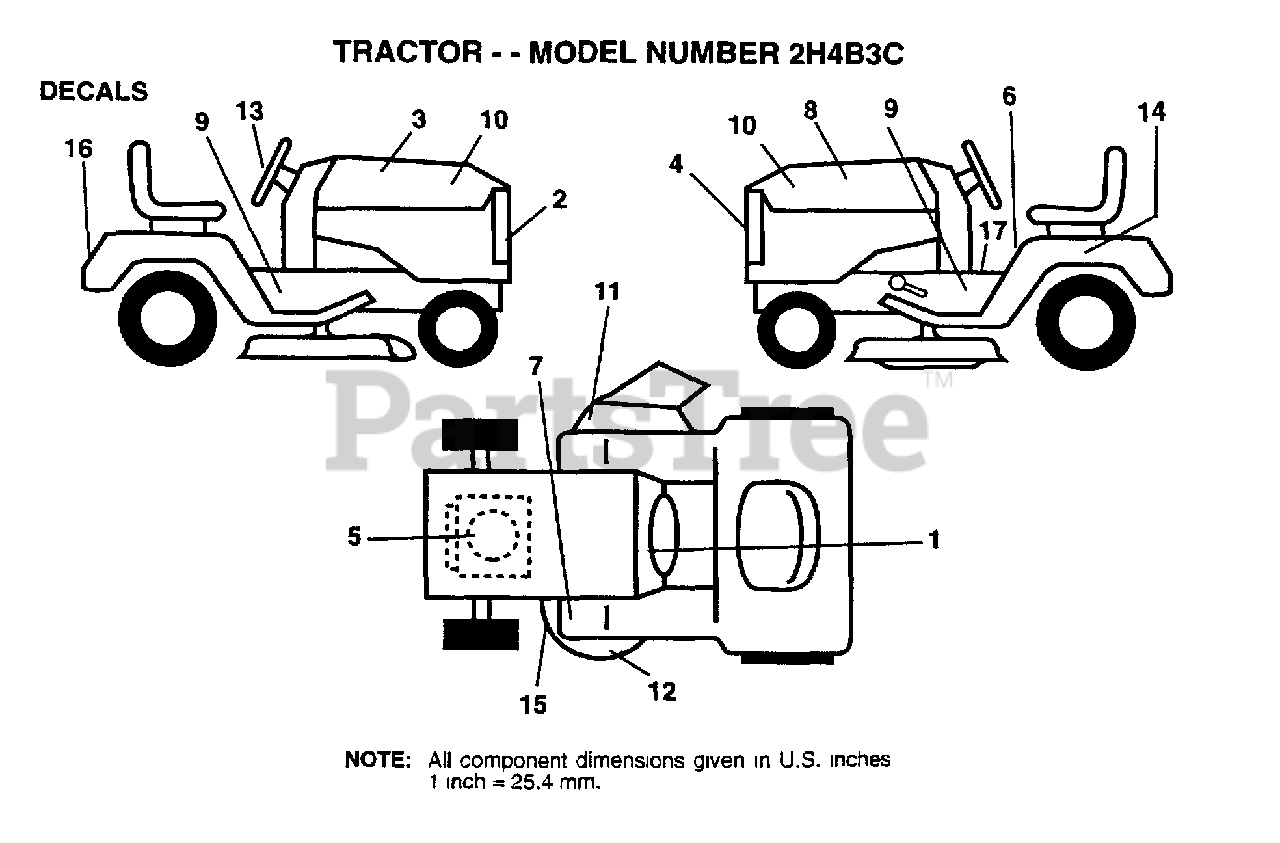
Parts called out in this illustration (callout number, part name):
1	DECAL.DASH.INSTR.
2	GRILL DECAL
3	DECAL HOOD RH RLY
5	DECAL.ENG.272632
6	DECAL CAUTION
7	DECAL T
8	DECAL HOOD LH RLY
9	CHASSIS DECAL
11	"DECAL, WARNING"
13	"DECAL,STR WHL"
14	DECAL
15	DECAL
16	FENDER DECAL
17	DECAL BRAK PARK
